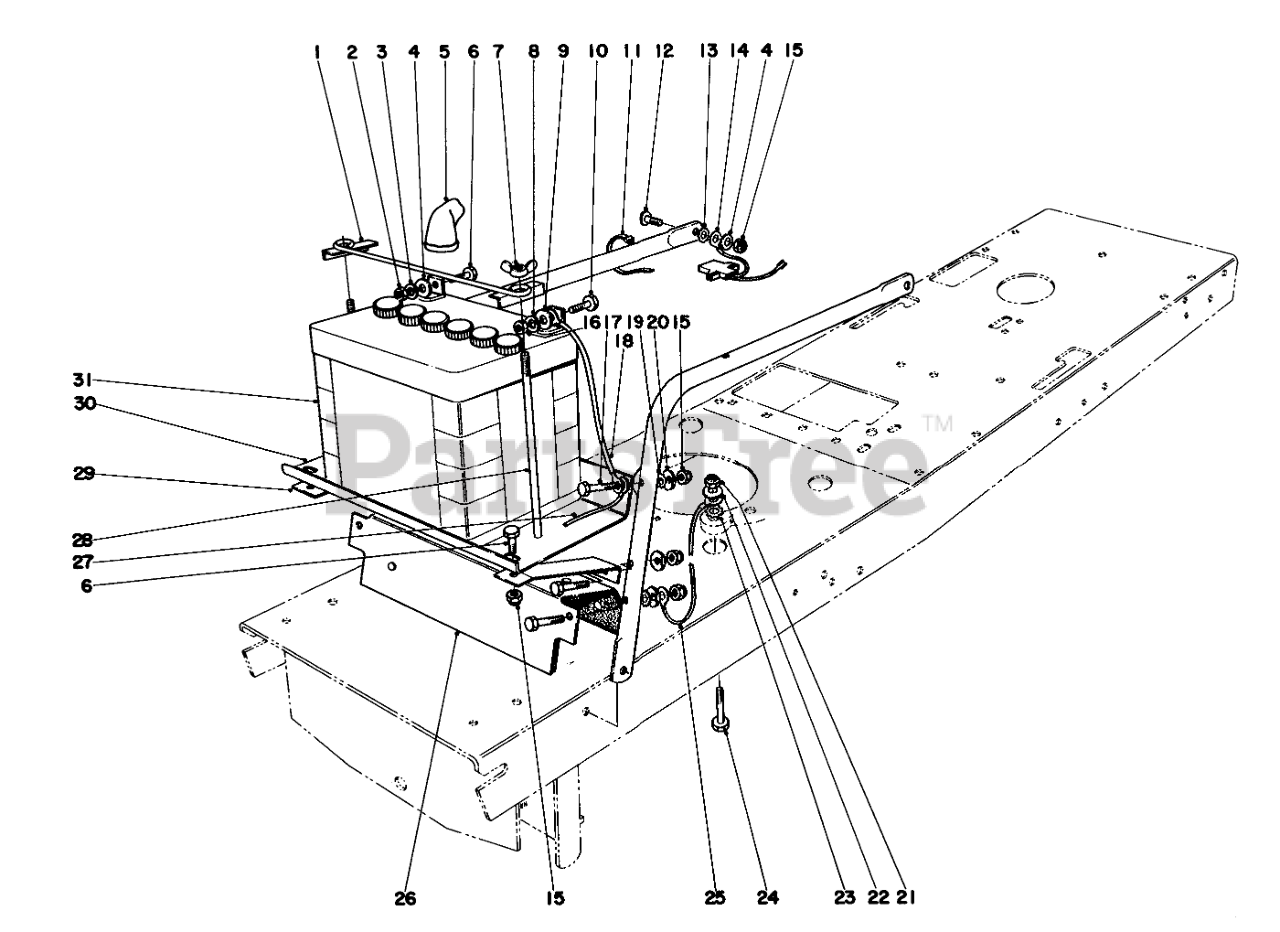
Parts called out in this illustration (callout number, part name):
1	Clamp Battery
2	NUT-HEX
3	WASHER-LOCK
4	WASHER-FLAT
5	BATTERY BOOT
6	SCREW-HH
7	WING NUT
8	WASHER-LOCK
9	WASHER-PLAIN
10	SCREW-HH
11	Cable Tie
12	BOLT-CARR
13	WASHER-LOCK/EXT
14	Wire Assy. Trimmer Receptacle
15	NUT-LOCK, CONE
16	NUT-HEX
17	SCREW-HH
18	Wire Assembly Battery to Ground
19	WASHER-LOCK/EXT
20	WASHER
21	NUT-LOCK, CONE
22	WASHER-PLAIN
23	WASHER-LOCK
24	SCREW-HH
25	Wire Assembly Engine to Ground
26	Heat Shield
27	Wire Assembly Headlight to Ground
28	BATTERY BOLT
29	Brace Battery Shelf
30	Battery Shelf
31	Battery
